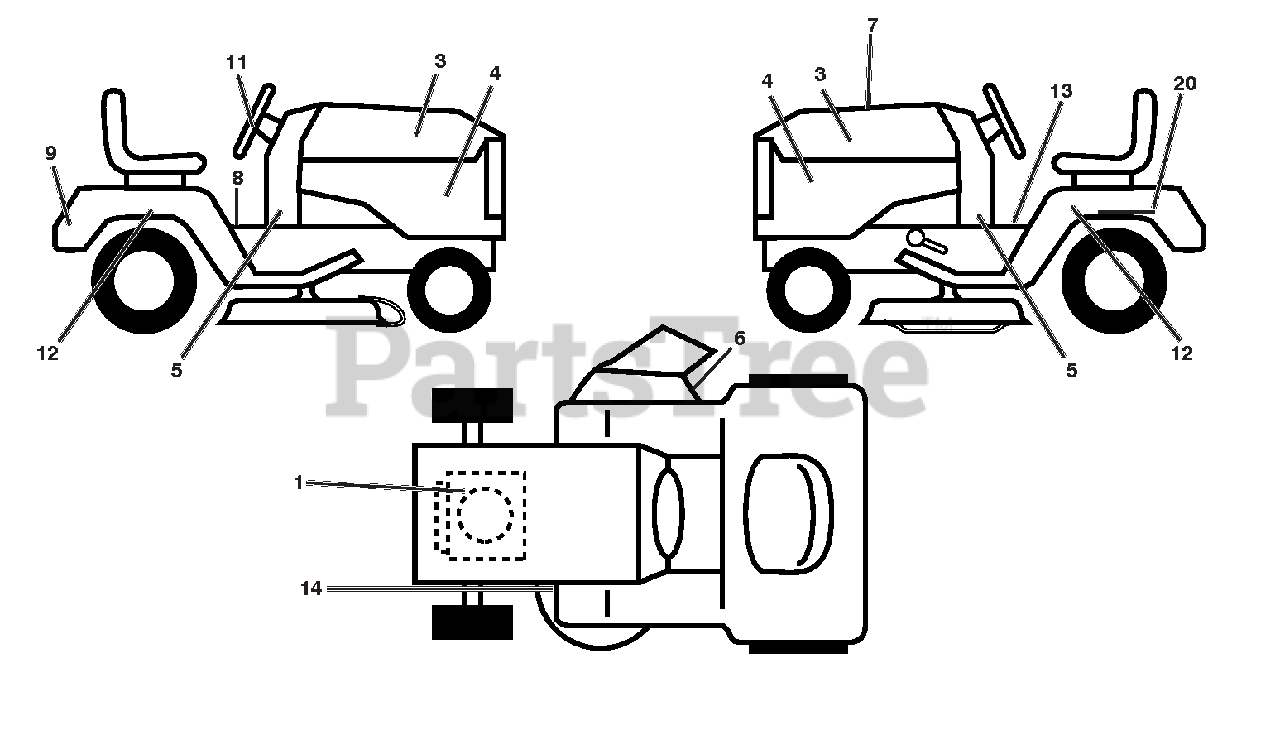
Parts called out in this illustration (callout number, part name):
1	DECAL ENGINE H.P.
3	DECAL.HOOD.LH/RH.
4	DECAL.SDPNL.PWRDBY B&S.ARIENS
5	DECAL.DASH.LWOWER.20HP.ARIENS
6	DECAL.MOWER.WARN.KEEP HAND AWY
7	DECAL.REPLACEMENT
8	DECAL, WARNING START INST.
9	DECAL.FENDER.REAR.ARIENS
11	DECAL.WHEEL.STEER.ARIENS
12	DECAL.FENDER.SIDE.HYDRO.ARIENS
13	DECAL.FENDER
14	DECAL.V-BELT.SCH.42/46"MEC/ELE
20	DECAL.BAT.DAN/POI P/L SYM.WPN
